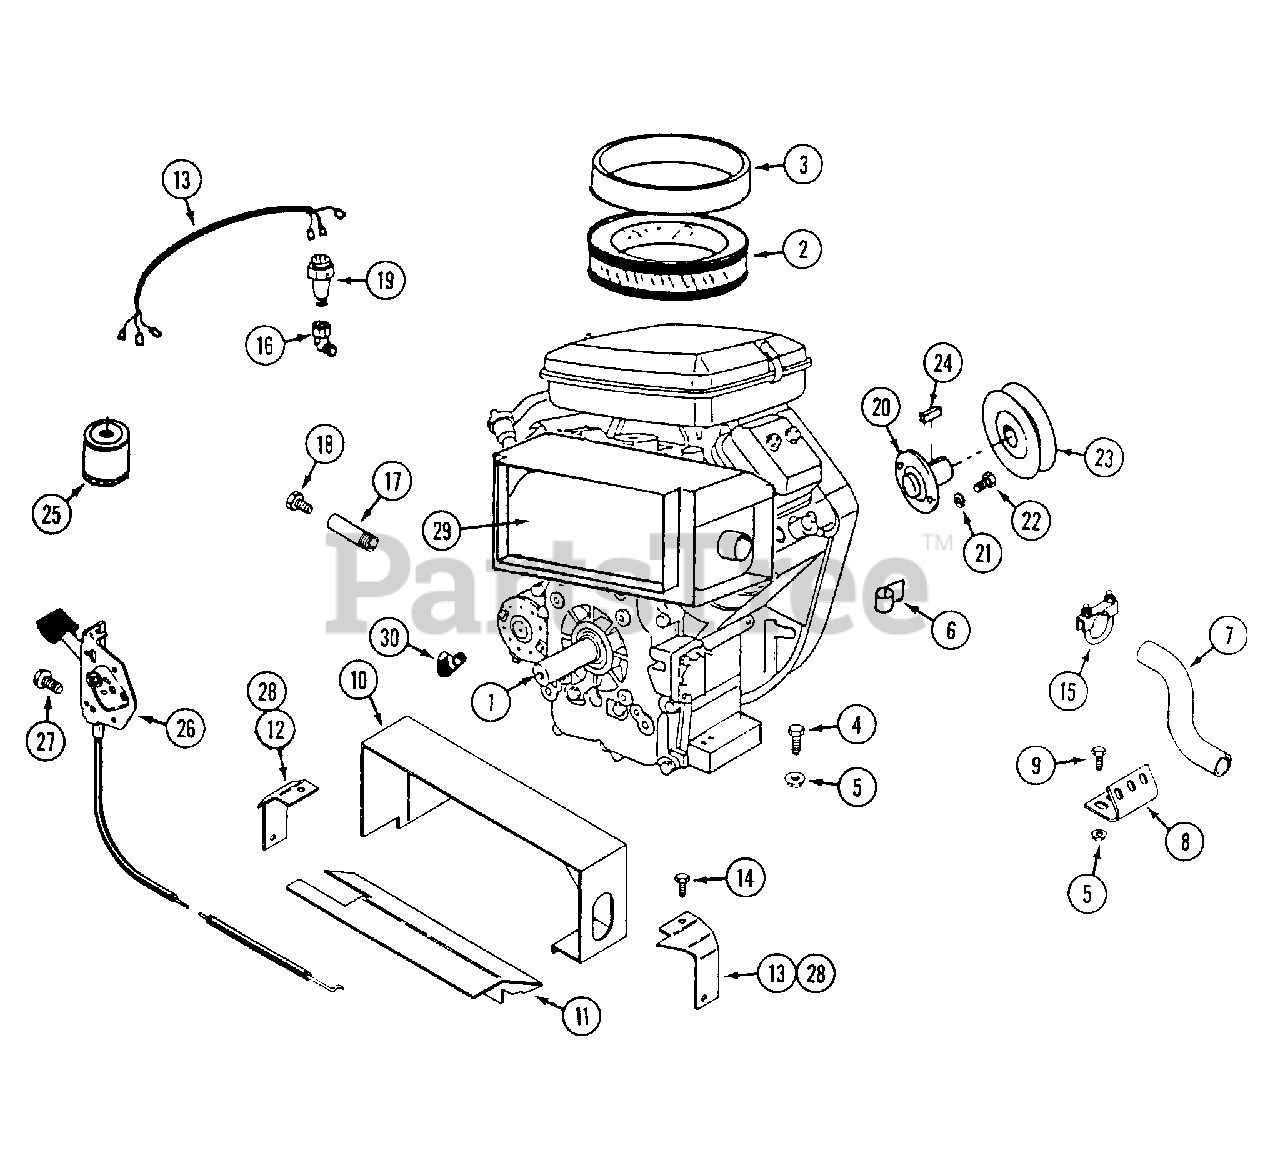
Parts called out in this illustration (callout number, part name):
1	ENGINE - Briggs & Stratton model 350447, type 0139 (18 hp)
2	ELEMENT - air cleaner
3	PRE-CLEANER
4	BOLT - 5/16" - 18 x 1-1/4"
5	NUT - 5/16" - 18 flange lock
6	CLIP - "J"
7	PIPE - exhaust
8	BRACKET - exhaust pipe
9	BOLT - 5/16" - 18 x 1"
10	DUCT - muffler, upper
11	DUCT - bottom
12	SUPPORT - duct, front
13	SUPPORT - duct, rear
14	SCREW - M6 x 10
15	CLAMP - exhaust
16	FITTING - street elbow, 1/4" NPT 45°
17	NIPPLE - pipe 3.5"
18	PLUG - 1/2" - 20
19	UNIT - oil sending
21	LOCKWASHER - 3/8"
22	BOLT - 3/8" - 16 x 1"
23	PULLEY - engine
24	KEY - 1/4" x 1/4" x 1"
25	FILTER - oil
26	CABLE - throttle
27	SCREW - #12 x 1/2"
28	BAFFLE - duct
30	COVER - terminal, starter
